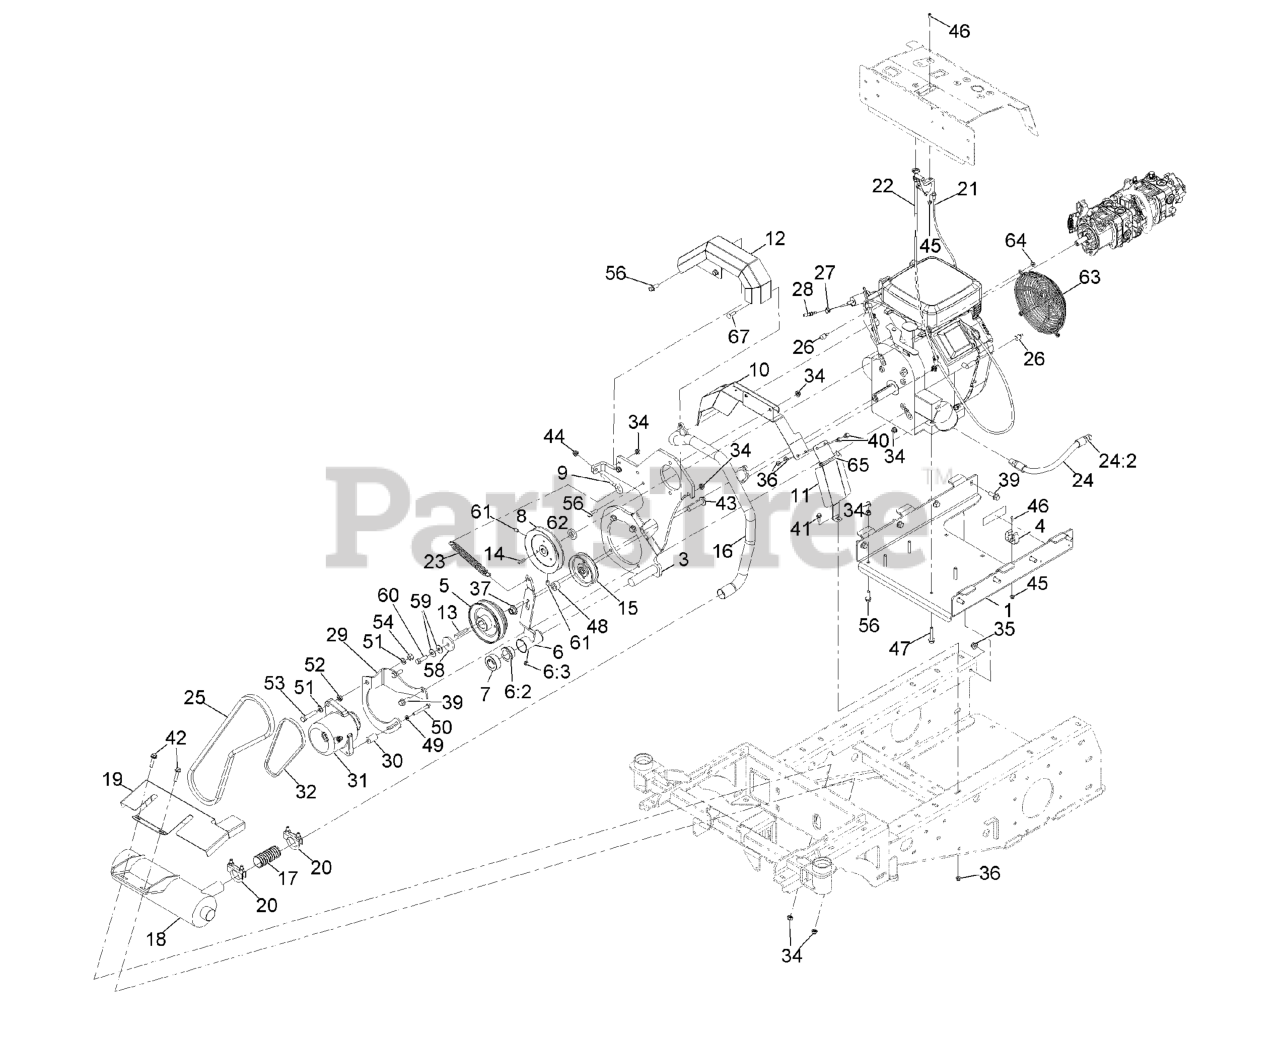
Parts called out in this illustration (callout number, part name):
1	Tray-Engine
3	Bracket-Engine, Pump [black]
4	Holder-Tool, Clip
5	Pulley-Double
6	Arm-Tension, ASM
6:2	BUSHING-FLANGE
6:3	FITTING-GREASE, ZERK
8	PULLEY-DRIVE, PUMP
9	Bolt-Eye
10	Guard, Lower Muffler
11	Guard, Lower Muffler
12	Guard-Pulley
15	PULLEY-IDLER, FLAT
16	Manifold-Exhaust
17	TUBE-EXHAUST, FLEX
18	MUFFLER
19	SHIELD-HEAT, MUFFLER
20	Clamp-Muffler
21	CABLE-THROTTLE
22	CABLE-CHOKE
23	SPRING-EXTENSION
24	ASM, Oil Drain Hose W/Plug
26	Tube-Heat Shrink, 1/2
27	CLAMP-HOSE
28	BARB-FUEL
29	Bracket-Alternator
30	TUBE-SUPPORT, ALTERNATOR
31	ALTERNATOR
32	Belt-V, 3L240
34	Nut-Hex Flange
35	Nut-Hex Flange
36	Nut-Hex Flange
37	Nut-Lock 1/2-13
39	SCREW-HHF
40	SCREW-HHF
41	Screw-HHF
42	SCREW-HHF
43	Screw-HHF
44	NUT-HF, NI
45	Nut-Hex Flange
46	Screw-HSBH
47	Screw-HHF
49	WASHER-LOCK
50	Screw-HH
51	Washer-Flat
52	Nut-Hex
53	Screw-HH
54	Nut-Lock, NI
56	SCREW-HHF
58	WASHER-PLAIN
59	WASHER-BELLEVILLE
60	Screw-HH
61	Setscrew-HSH
63	GUARD-WIRE, VANGUARD
65	TIE-CABLE
67	Bolt,Carriage,5/16-18X1,ST/ST 18-8
